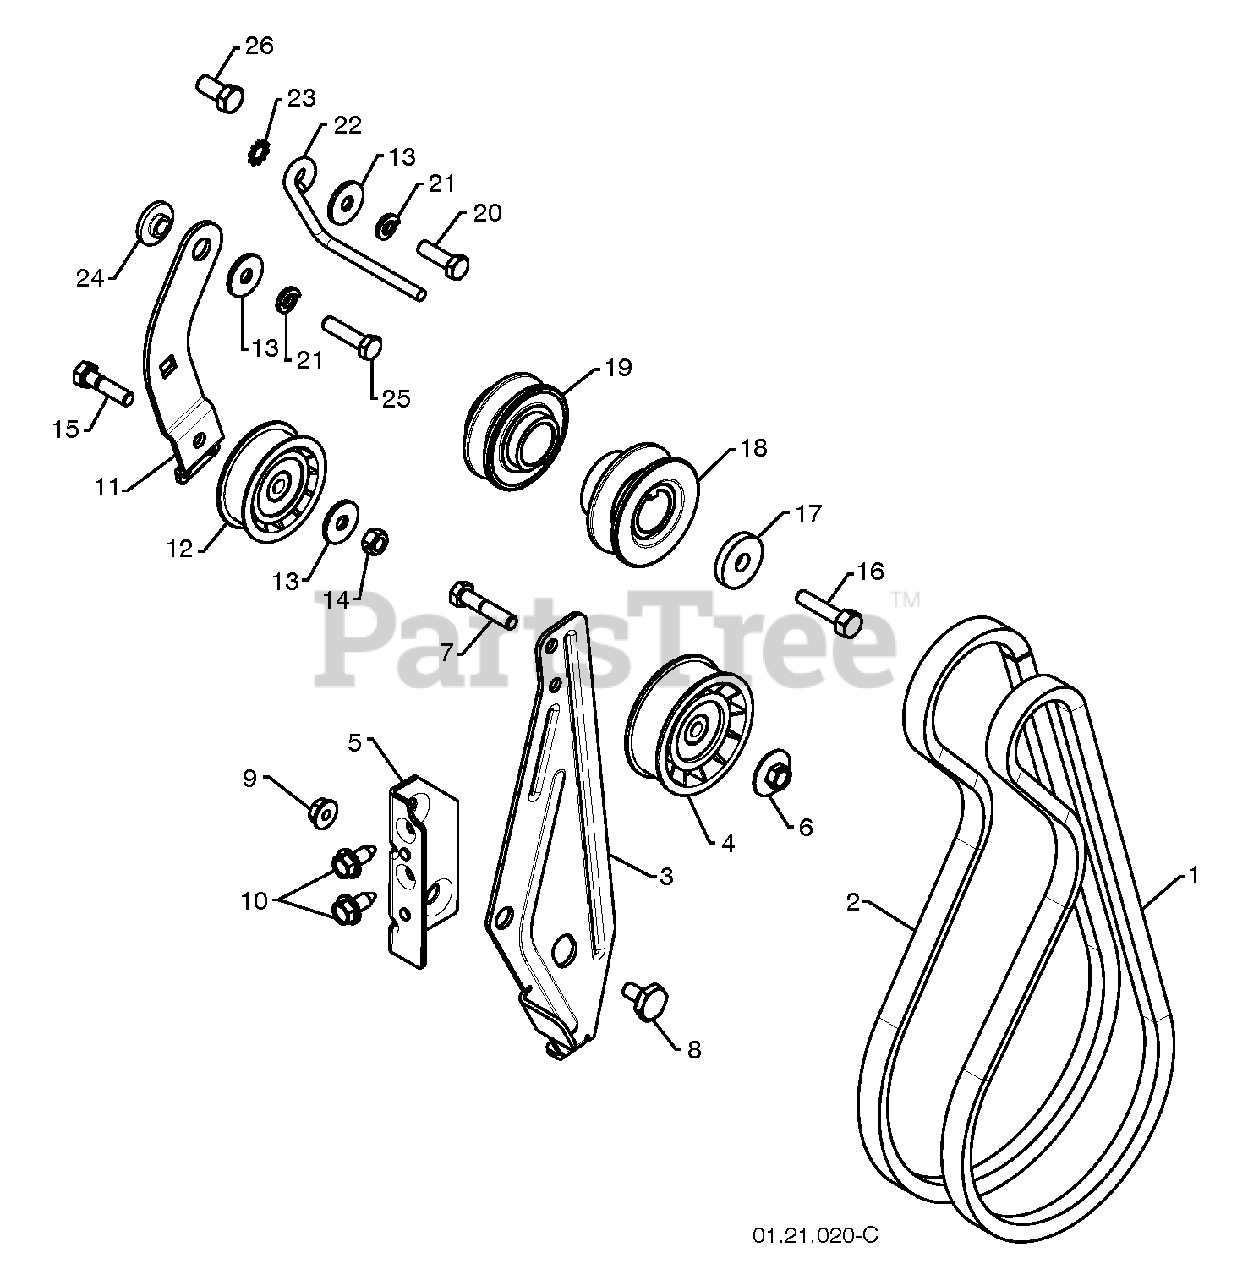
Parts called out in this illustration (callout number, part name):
1	V-BELT.IMPELLER
2	TRACTION BELT
3	ARM.IDLER.BRAKE.
4	PULLEY.W/SPACER.2.75
5	RP BRACKET.IDLER.PIVOT
6	NUT.FLANGE.HEX.5/16X18.BLACK
7	HEX BOLT
8	BOLT.SHOULDER.1/2X12
9	NUT.LOCK.5/16-18
10	BOLT.5/16HEX.WHS.HD
11	ARM, IDLER
12	PULLEY.W/SPACER.2.25
13	STEEL WASHER
14	NUT.71038.31-18.HEX.NYLOCK
15	BOLT.5/16-18X1-1/4 FULL.THREAD
16	SCREW, HEX HD 3/8-24 X 1-3/8
17	WASHER.400X1.25X5.
18	PULLEY ENG IMPELLER
19	PULLEY.ASM.ENG.TRACTION.1.00
21	LOCKWASHER
22	BELT.GUIDE.RH
23	WASHER EXT TOOTH LOCK 5/16
24	RP BUSHING, IDLER PIVOT
25	SCREW.3/8-16 X .750 (2 2)
26	CAPSCREW.HEXHD.5/16X1.25.
